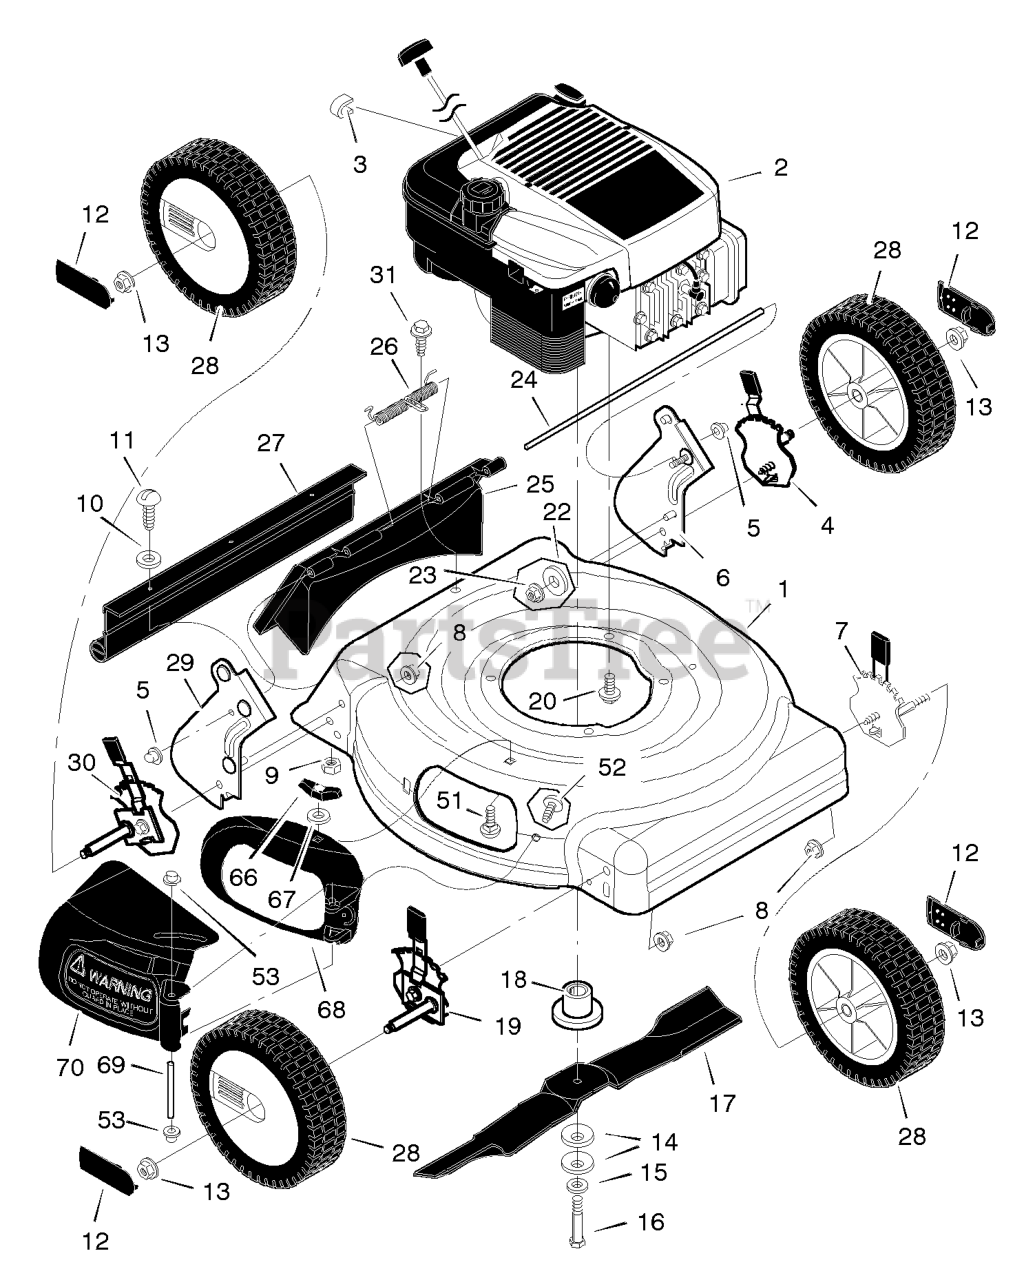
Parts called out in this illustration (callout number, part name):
1	Housing
2	Engine *
3	Stop, Rope (Recoil - Start)
4	Adjuster, Left Rear Height
5	Nut, Push
6	Bracket, Left Handle
7	Adjuster, Left Front Height
8	Nut, Flange
9	Nut, Hex
12	Hub Cap
13	Nut, Flange
14	Washer, Belleville
18	Adapter, Blade
19	Adjuster, Right Front Height
20	Bolt, Engine
22	Washer
23	Nut, Flange
24	Rod, Pivot
25	Door, Rear
27	Guard, Rear
28	Wheel (Dark Gray)
29	Bracket, Right Handle
30	Adjuster, Right Rear Height
51	Bolt, Carriage
53	Push On Cap
66	Wingnut
67	Retainer, Push
69	Pin, Pivot
70	Deflector, Chute
